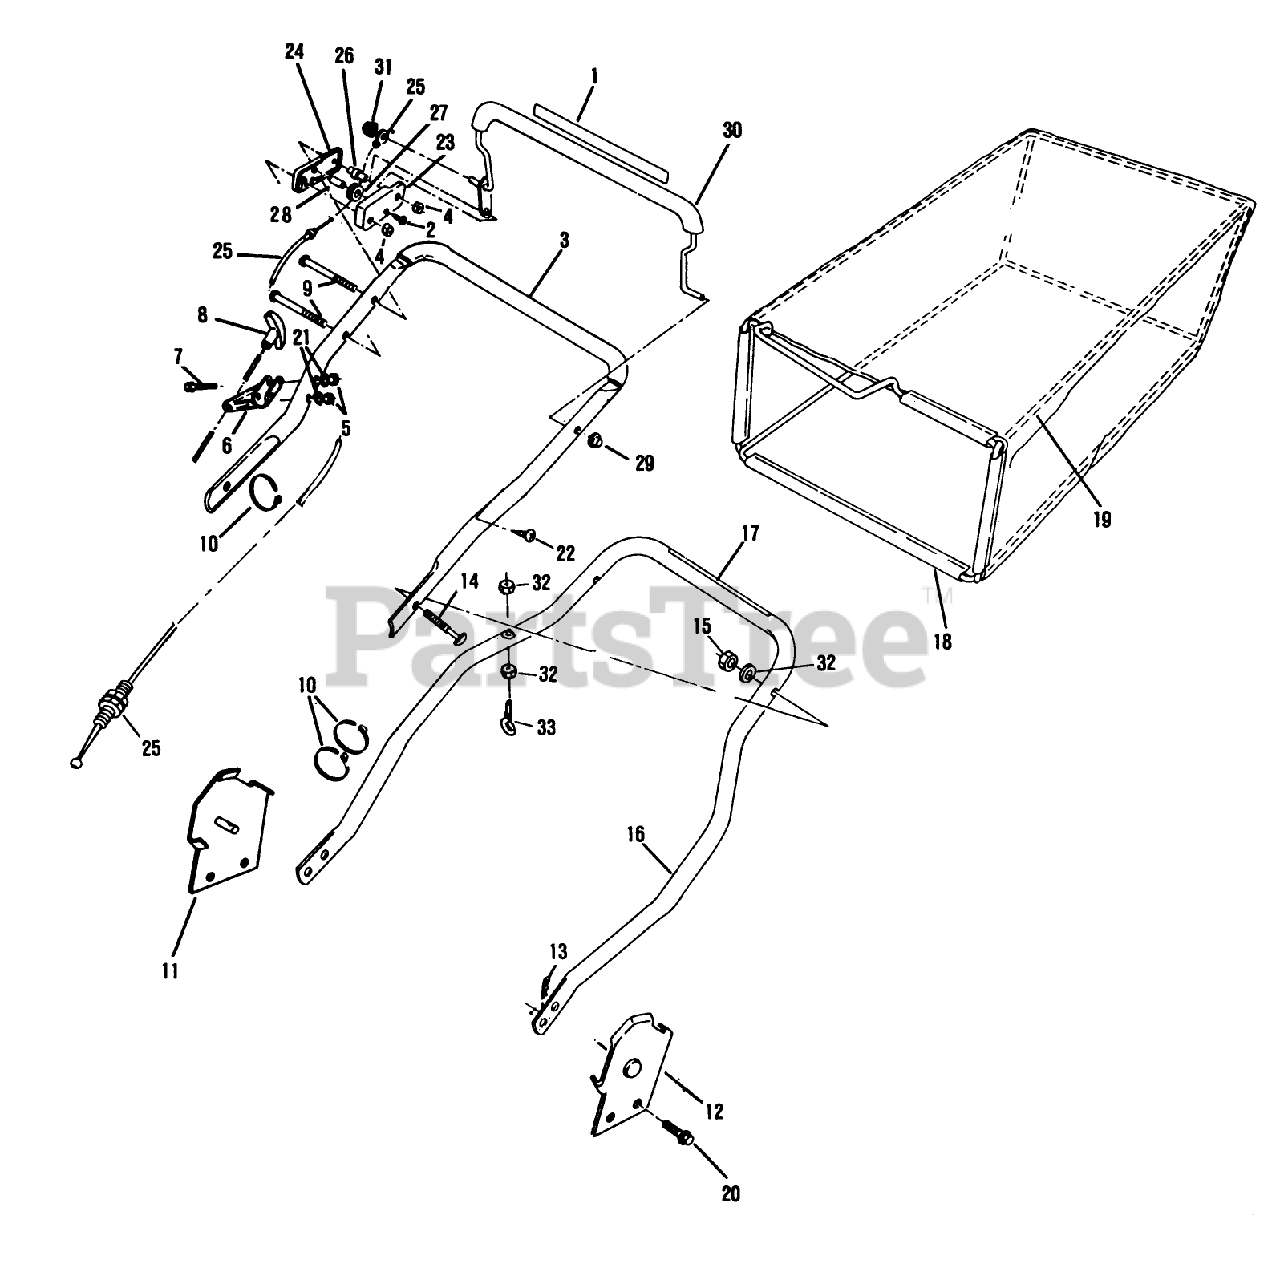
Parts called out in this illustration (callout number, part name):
2	SCREW
3	HANDLE-TOP *G
4	NUT C/LOCK E
5	LOCKNUT E
8	HANDLE,STARTER
13	HAIR PIN
15	NUT-LOCK F
21	WASHER
22	SCREW LAWRENCE
25	CONTROL CABLE WES
26	COLUMN
28	PIN SKF
31	NUT ACORN
32	WASHER-CURVED
33	EYE BOLT WAS MFG
